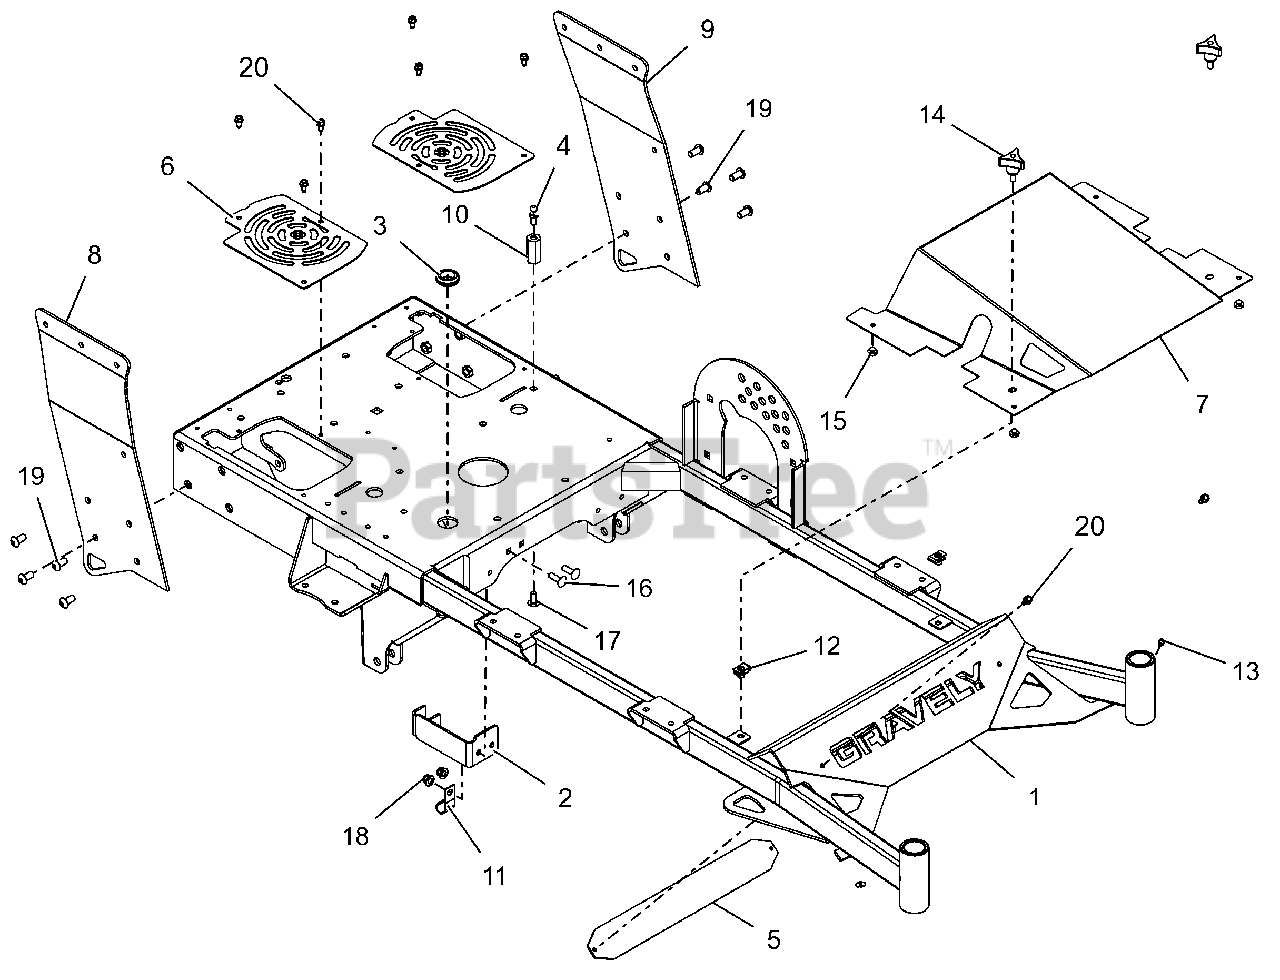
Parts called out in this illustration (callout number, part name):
1	WLDMT,FRAME 36" HYDRO PRO-WALK
2	WLDMT, CLUTCH STOP
3	GROMMET:RUB:.88IDX1.38ODX.14GR
4	STUD- BALL
5	BACKER, NAMEPLATE
6	COVER, 36" COOLING FAN
7	KIT, 36" FRONT SHIELD W DECALS
8	PANEL, RH 36" TANK TOWER
9	PANEL, RH 36" TANK TOWER
10	SPCR, DAMPENER MTG
12	NUT-CLIP RETAINER 5/16-18X.56
13	FTG-LUBE .25-28X.256 SST
14	KNOB,WING STUD 5/16-18 X .75
15	BUMPER GROMMET
16	@BLT-RHDSSQNK .31-18X1.00 G5YZ
17	@BLT-RHDSSQNK .31-18X.75 G5YZ
18	@NUT-LK-NYL-FLG .31-18 YWZC
19	BLT-BTHD-SOCKET .38-16X.75
20	SCR-TAP .25-20X.50 HWH TR YWZ
